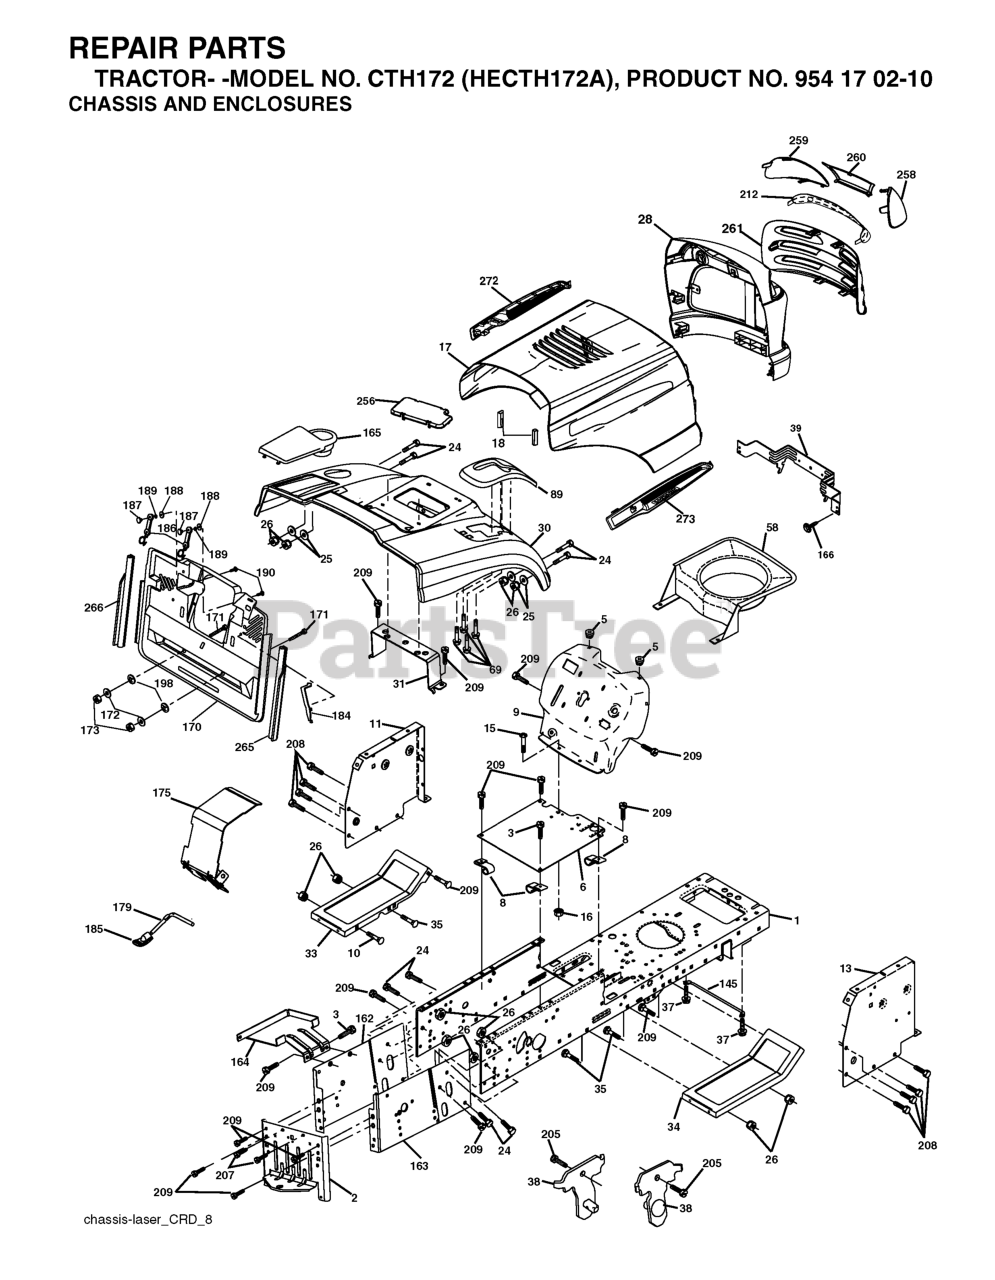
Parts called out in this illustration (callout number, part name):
2	DRAWBAR
3	SCREW 3/8-16X3/4
5	BUMPER.RUBBER.HOOD
6	PLATE
8	CLIP,INSULATOR
10	BOLT D
11	PANEL.DASH.LH.LTX
13	PANEL ASM, DASH RH
15	Screw, Machine, Truss Head 5/16-18 UNC x 3/4
16	NUT
17	VENT.HOOD.LASER.III
18	BUMPER.HOOD.LARGE.1.75"
25	WASHER
26	NUT
31	BRACKET SUPPORT FENDER
33	FOOTREST PNT LH
34	FOOTREST PNT RH
37	Screw 5/16-18 x 1/2 Hex, Self Tapping 5/16-18 x 1/2
38	BRACKET ASM PIVOT MOWER REAR
39	BRACKET PIVOT LASER
69	SCREW.HI-LO.CONSOLE
89	COVER.BATTERY.CRD.GREY
145	ROD PIVOT CHASSIS/HOOD
162	BRACKET
163	BRACKET EXTEN CHASSIS RH CRD
165	RP.COVER.BATTERY.CRD.GREY
166	SCREW
172	WASHER
175	DOOR TRAP
179	ROD PIVOT FBI
184	BRACKET.ACTUATOR.BAGGER.SRD
186	LATCH ASSY
187	WELDNUT
189	LOCKWASHER #10
190	SCREW
207	SCREW, 5/16-18 X 1/2
208	SCREW 3/8-16X1/2
209	SCREW, 3/8-16X3/4
212	INSERT.LENS.REFLECTIVE
256	COVER FENDER CRD
258	LENS LH
259	LENS LH
260	COVER.LENS.HUSQ.LASER
265	SEALING
266	SEALING
272	VENT.HOOD.LASER.
273	VENT.HOOD.LASER.
